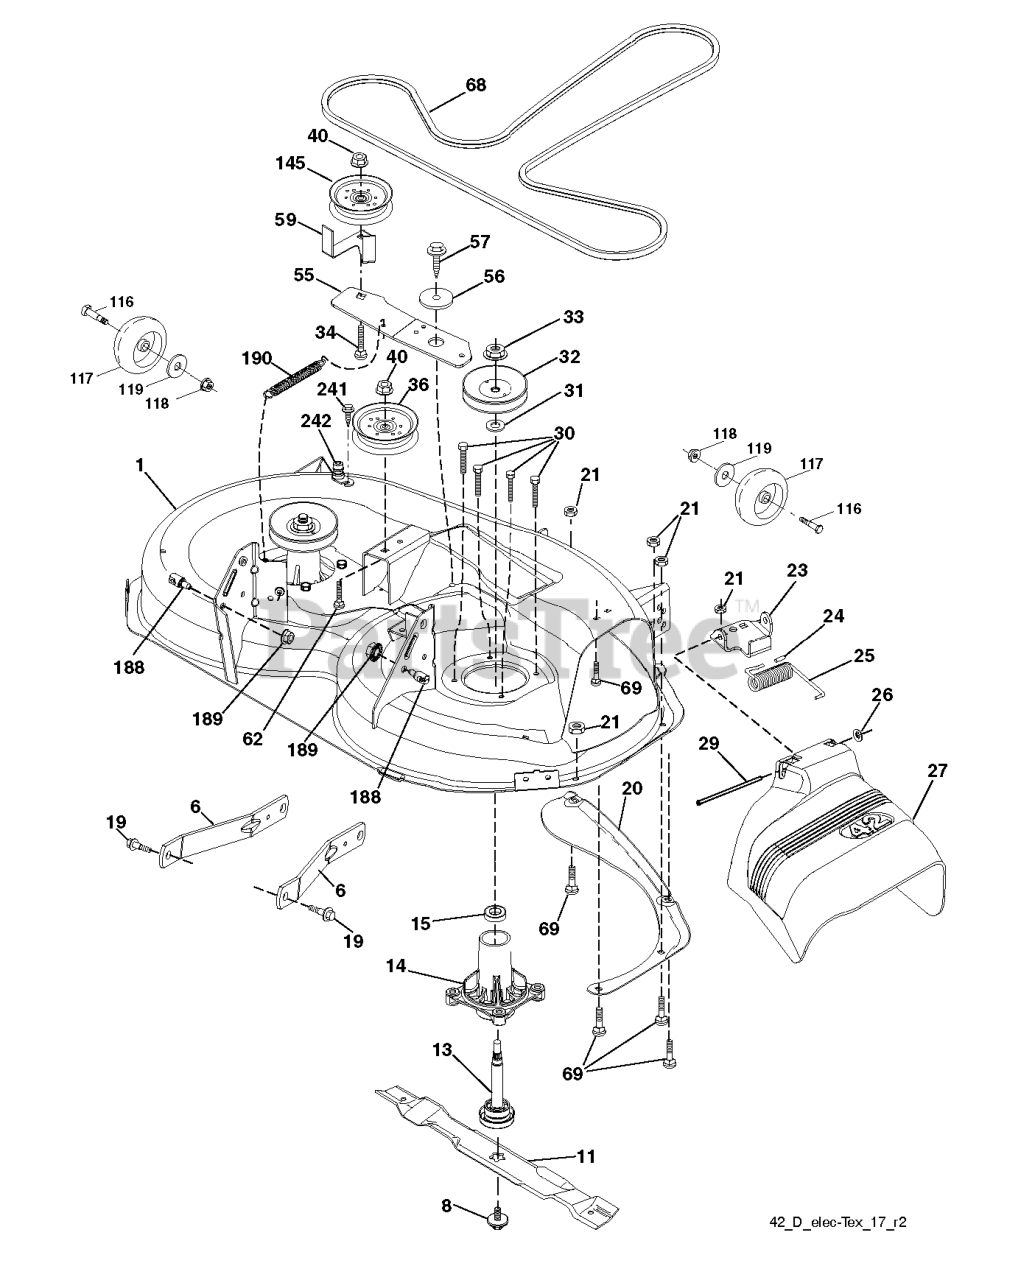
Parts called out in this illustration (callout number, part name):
1	DECK.WELDMNT.42"GREYMS498
6	ARM.SUSPENSION.MOWER.R
8	BOLT.WASHER.ASM.7/16-2
11	42" HI-LIFT BLADE
13	SHAFT.ASM.MDRL.N/GREASE.38
14	RP.HOUSING.MANDREL.4PT.
19	BOLT.SHOULDER
20	BAFFLE.VORTEX
21	LOCKNUT
23	BRKT.DEFLECTOR.38"2005+
24	CAP-SLEEVE LT
25	SPRING.TORSION.DEFLECT
26	NUT PUSH M
27	SHIELD.DEFLECTOR.MOWER.42"BLAC
29	ROD.HINGE
30	SCREW, WASHER HEAD
31	WASHER.SPACER.MANDREL
32	PULLEY/MANDREL
33	NUT.FLANGE.LOCK.TOP
34	BOLT.3/8-16X1.50
36	PULLEY.IDLER.2006
40	NUT LOCK FLG 3/8-16 UNC
55	IDLER.ARM.42"
56	SPACER.RETAINER
57	SCREW 3/8-16X1
59	GUARD, BELT
68	BELT V SECONDARY
69	BOLT
116	BOLT M
117	WHEEL.GAGE.HALF.SPOKED
118	NUT LOCK FLG 3/8-16 UNC
119	WASHER.5/16.FLAT.STE.STD.
145	PULLEY.IDLER.48"PRIMARY
188	STUD.FASTNER.W/ANTI-ROTATE
189	NUT LOCK HEX FLANGE 5/16-18
190	SPRING.MOWER.DRIVE.ELECTRIC
241	SCREW.TT.#10-32X.5.3/8.FLANGE
242	PORT.WASHOUT
